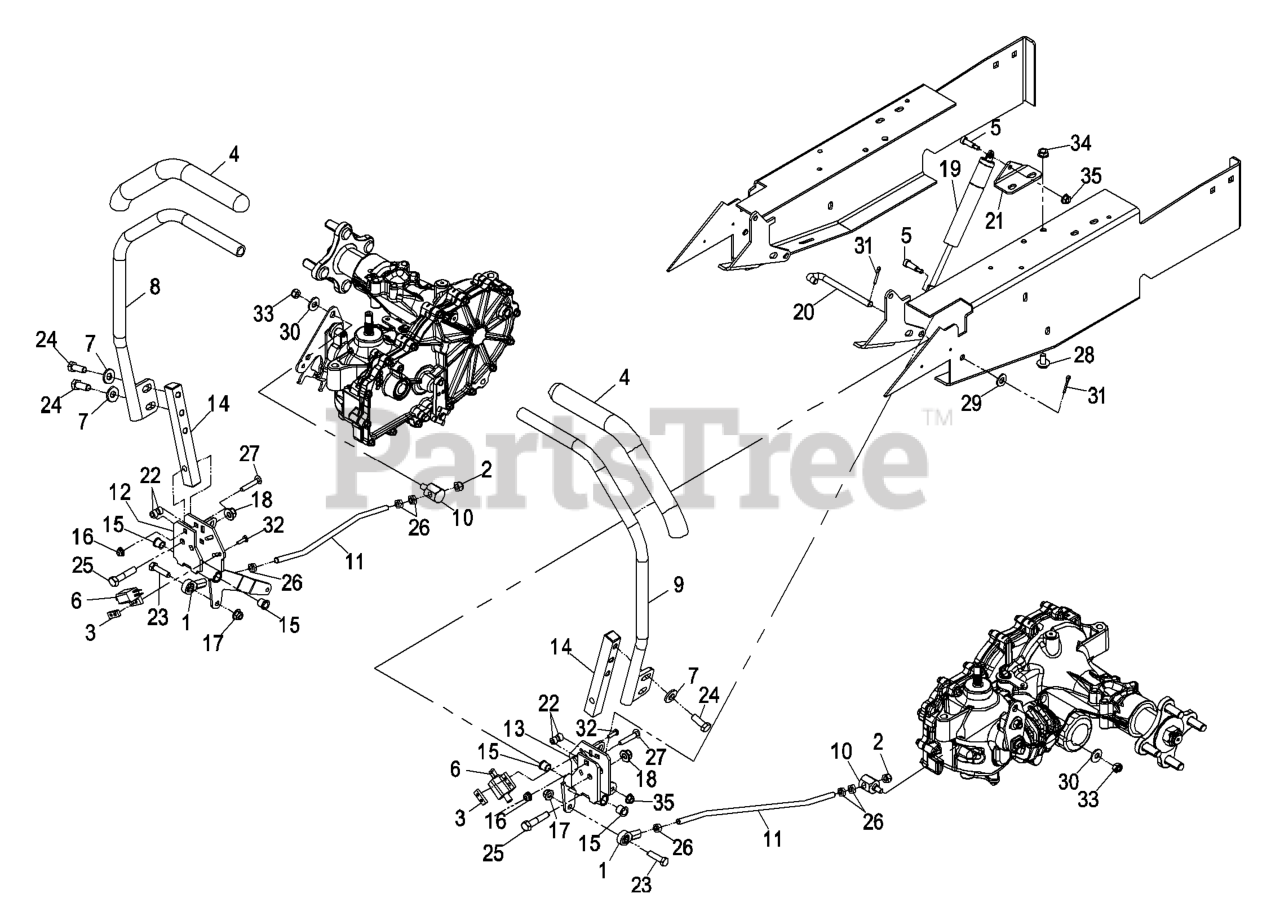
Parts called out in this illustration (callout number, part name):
1	BALLJOINT-RH
2	NUT-LOCK
3	PLATE-TAPPED
4	GRIP-CONTROL, MOTION
5	SCREW-HSH
7	WASHER-BELLEVILLE
8	ASM,LEVER CONTROL RH
9	ASM,LEVER CONTROL LH
10	TRUNNION
11	ROD-STEERING, LH
12	CONTROL-STEERING, RH
13	CONTROL-STEERING, LH
14	MOUNT-POST, LEVER
15	BEARING
17	NUT-HF, NI
18	NUT-HF, NI
19	DAMPER-CONTROL, MOTION
20	SHAFT-PIVOT, CONTROL
21	BRACKET-DAMPER
23	SCREW-HH
24	SCREW-HH
25	SCREW-HH
26	NUT-JAM
27	SCREW-CARR
28	SCREW-HHF
29	WASHER-FLAT
30	WASHER-FLAT
31	PIN-COTTER
32	SCREW-PPH
33	NUT-LOCK, NI
